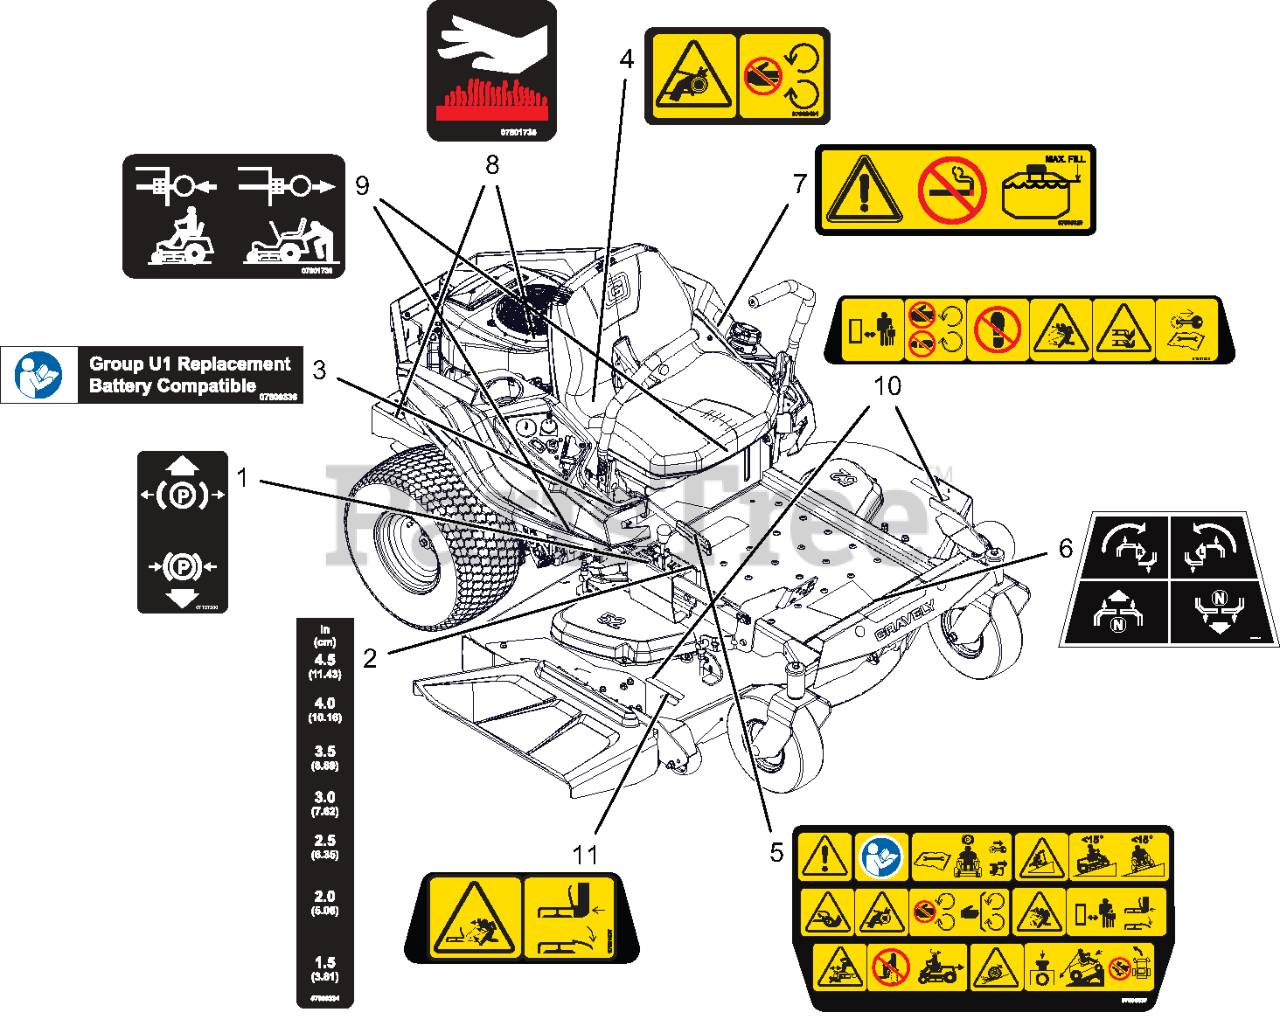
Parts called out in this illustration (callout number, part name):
1	DECAL, PARKING BRAKE LEVER
2	DECAL, HEIGHT OF CUT
3	DECAL, U1 BATTERY REPLACEMENT
4	DECAL, SAFETY - GUARDING
5	DECAL, MAIN SAFETY
6	DECAL, STEERING
7	DECAL, FUEL WARNING
8	DECAL,SAFETY HOT SURFACE
9	DECAL,TRANSAXLE DISCONNECT
10	DECAL- SAFETY - MOWER DECK
11	DECAL- SAFETY - DECK GUARDING
